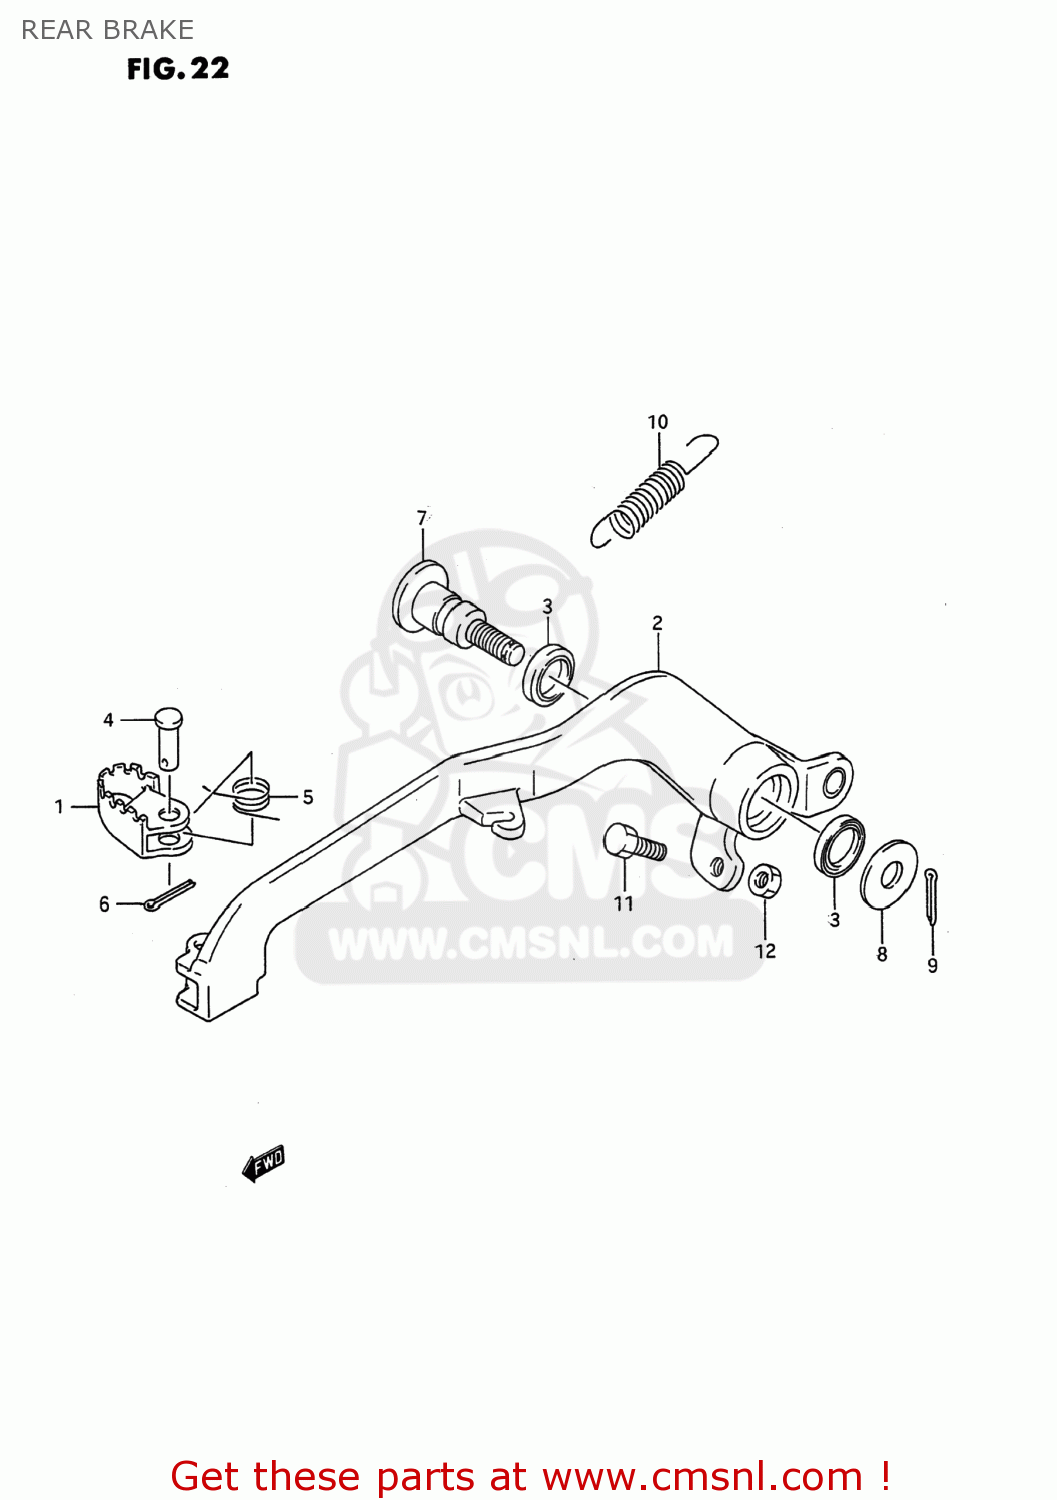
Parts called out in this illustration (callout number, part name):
1	PEDAL,BRAKE
2	ARM,BRAKE PEDAL
3	SEAL,OIL(15X21X3)
4	PIN(6X23.5)
5	SPRING
6	PIN
7	SHAFT,BRAKE PEDAL
8	WASHER
9	PIN 20X20
10	SPRING
11	BOLT(6X23)
12	NUT
